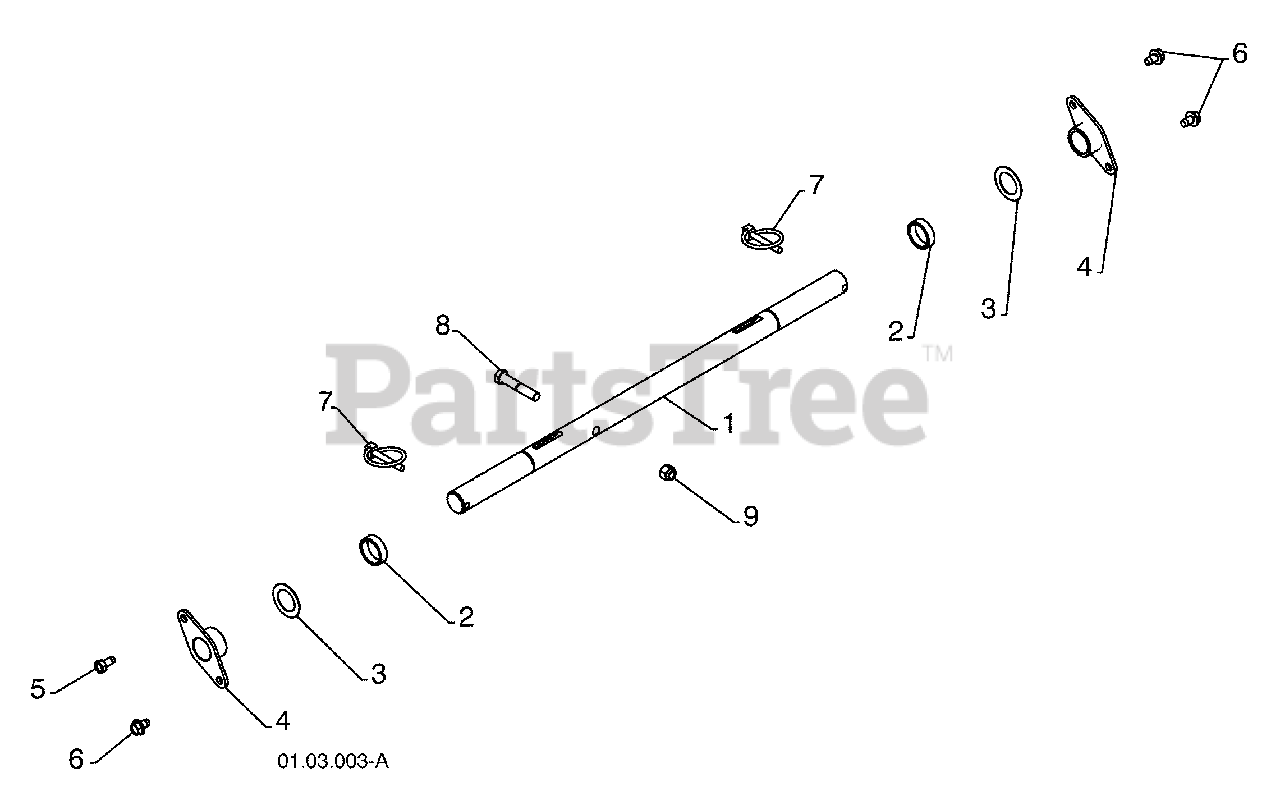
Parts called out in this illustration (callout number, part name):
1	AXLE SHAFT
3	THRUST WASHER
5	SCREW 5/16-18 X .625
6	BOLT 5/16-18 X .500
8	SCREW 3/8-16 X 2.00
9	NUT 3/8-16
